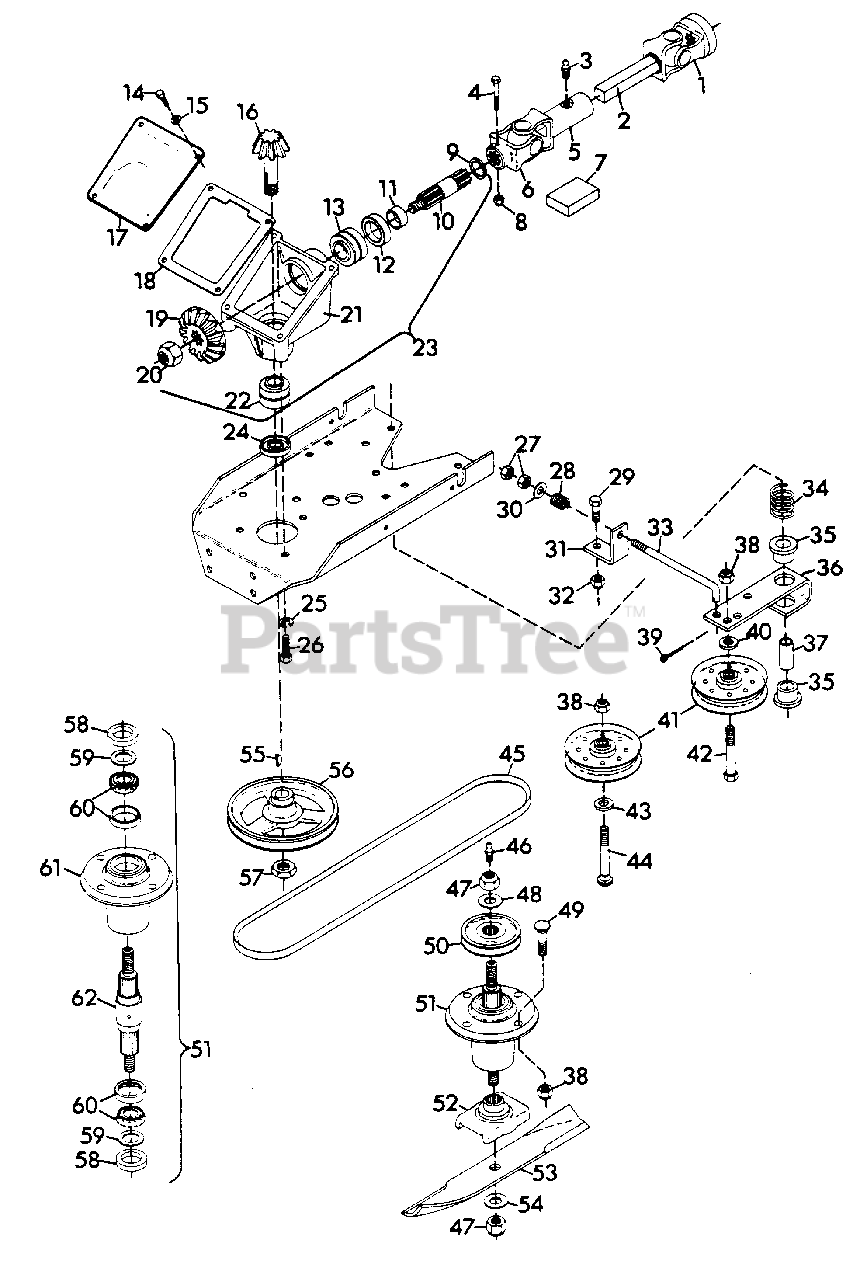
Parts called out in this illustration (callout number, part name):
1	YOKE
2	SHAFT, PROP. SQ. BAR
3	FITTING, LUBE 1/4-28
4	BOLT, HEX 1/4-20X2
5	U-JOINT, FEMALE END
6	YOKE(NEAPCO)
6	YOKE(ROSCOMMON)
7	KIT, REPAIR U-JOINT(ROCK STD.)
7	KIT, REPAIR U-JOINT(NEAPCO)
8	NUT, LOCK 1/4-20
9	RING, RETAINING 1.000 SHAFT
10	SHAFT, DRIVE
11	SPACER
12	SEAL, OIL 1.25X1.987X.250
13	ASSEMBLY, BEARING 1.000X1.980X1.243
14	BOLT, HEX 1/4-20X.50
15	WASHER, LOCK 1/4
16	SHAFT, GEAR PINION
17	COVER, GEAR HOUSING
18	GASKET, GEAR HOUSING
19	GEAR, BEVEL
20	NUT, LOCK 3/4-10
21	CASTING, GEAR BOX
22	ASSEMBLY, BEARING .750X1.781X1.499
23	ASSEMBLY, DRIVE 50" MOWER
24	SEAL, OIL 1.250X1.686X.313
25	WASHER, LOCK 1/2
26	BOLT, HEX 1/2-13X1.00
27	NUT, HEX 3/8-24
28	SPRING, COMP. TYPE 1X.78X338 LB/IN
29	BOLT, HEX 1/2-13X1.375
30	WASHER, FLAT .406X.812X.065
31	SUPPORT, SPRING
32	NUT, HEX 1/2-13
33	ROD, IDLER
34	SPRING, COMP.
35	BUSHING, NYLON .760X1.00X.600
36	ARM, IDLER PIVOT
37	SPACER
38	NUT, LOCK 3/8-16
39	PIN, COTTER 3/32X1.00
40	SPACER, IDLER .406X.750X.188
41	SHEAVE, IDLER
42	BOLT, HEX 3/8-16X2
43	WASHER, FLAT .438X1.000X.083
44	BOLT, 3/8-16X1.75 RD HD SQ NK
45	BELT, V .500X.312X126.3
46	FITTING, LUBE 1/8(LEFT AND RIGHT SPINDLE)
46	FITTING, LUBE .125 EXT.(CENTER SPINDLE)
47	NUT, LOCK 5/8-11
48	WASHER, FLAT .687X1.312X.122/.146
49	BOLT, 3/8-16X1.25 RD HD SQ NK
50	SHEAVE, SPINDLE
51	ASSEMBLY, SPINDLE
52	WELDMENT, BLADE CRADLE
53	BLADE
54	WASHER, FLAT .656X1.312X.095
55	KEY, WOODRUFF .188X.625 HARD
56	SHEAVE, 1/2X6.50
57	NUT, JAM 3/4-10 HEX HEAVY
58	SEAL, STEEL
59	WASHER, FLAT .975X1.970X.036
60	ASSEMBLY, BEARING
61	HOUSING, BEARING
62	SHAFT, SPINDLE
NS	SPRING
NS	COLLAR, LOCKING
NS	RING, SNAP
NS	BALL, DETENT
